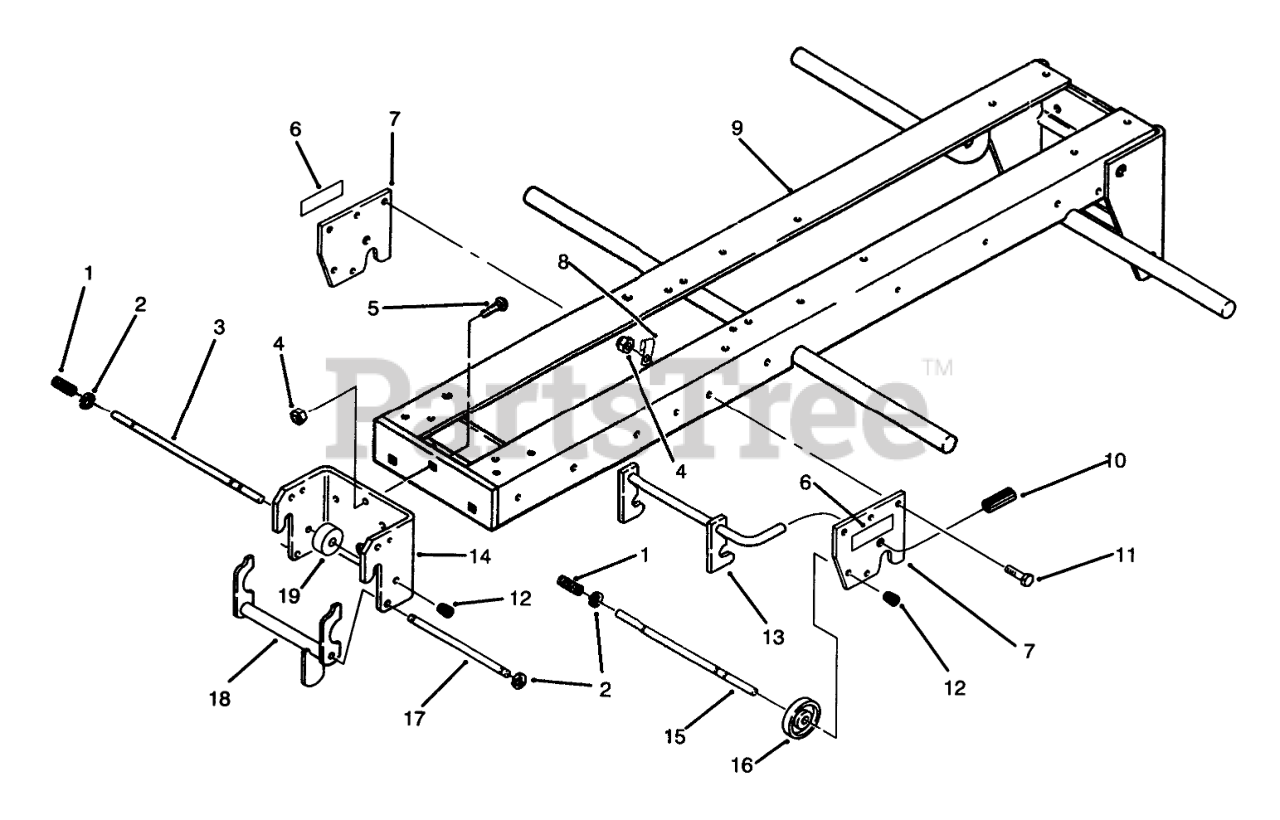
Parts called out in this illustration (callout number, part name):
1	SPRING
2	RING-RETAINING
3	ROD-LOCK
4	NUT-LOCK, NI
5	BOLT-CARR
6	DECAL-ATTACH A-MATIC
7	Hitch Plate
8	CLIP
9	WELD FRAME R
10	GRIP
11	SCREW-HH
12	CAP-ROD, PLUNGER
13	MID HITCH ASM
14	Front Hitch
15	ROD-LOCK
17	ROD-LATCH PIVOT
18	LATCH
